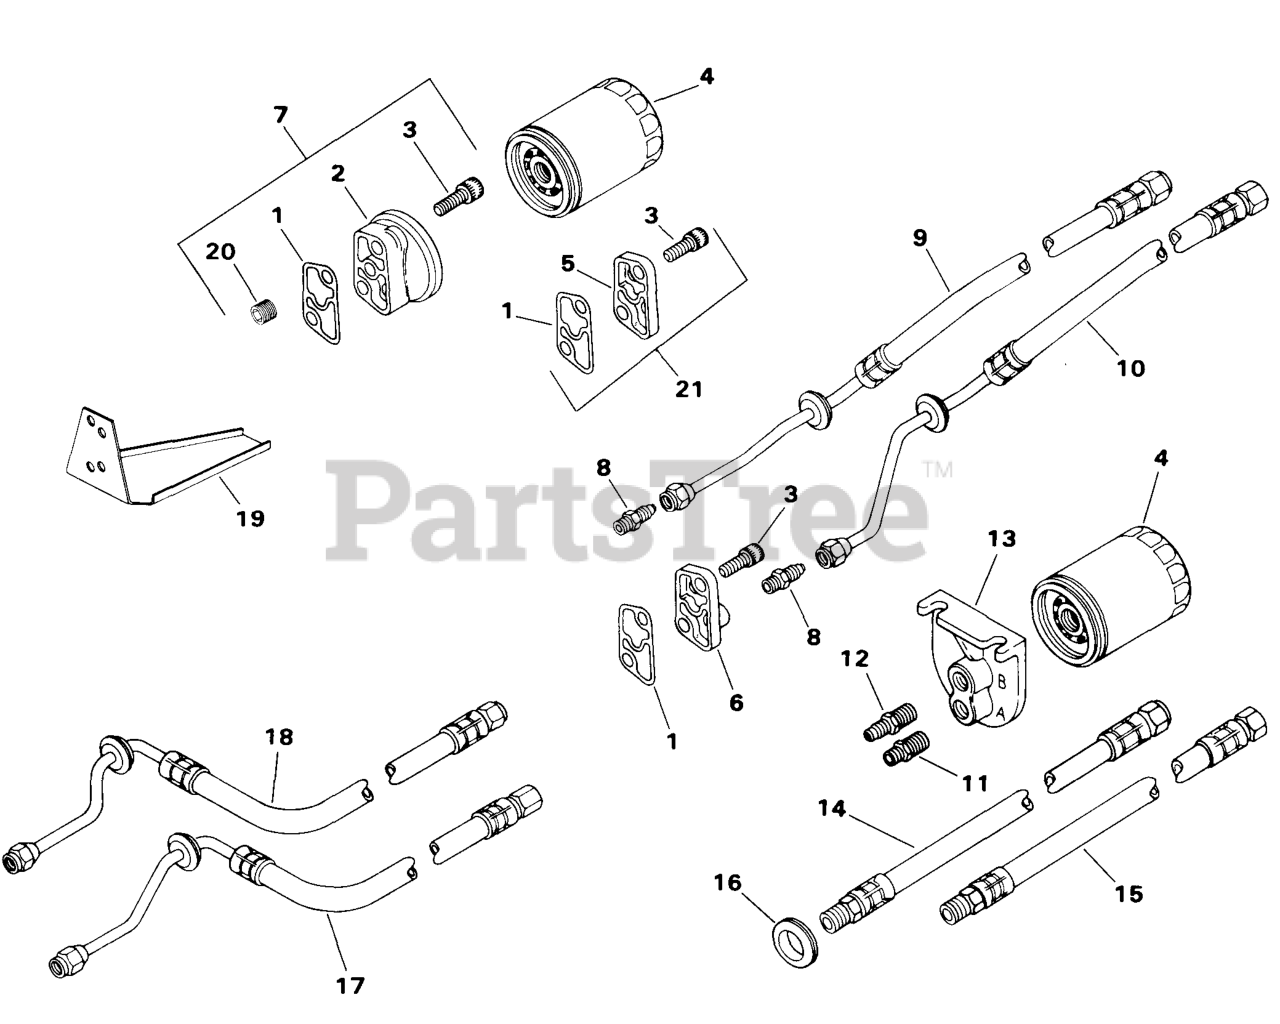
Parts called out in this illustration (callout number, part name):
2	Adapter
3	Screw, Hex. Socket Hd. Cap 5/16-18x1-1/4"
4	Oil Filter
